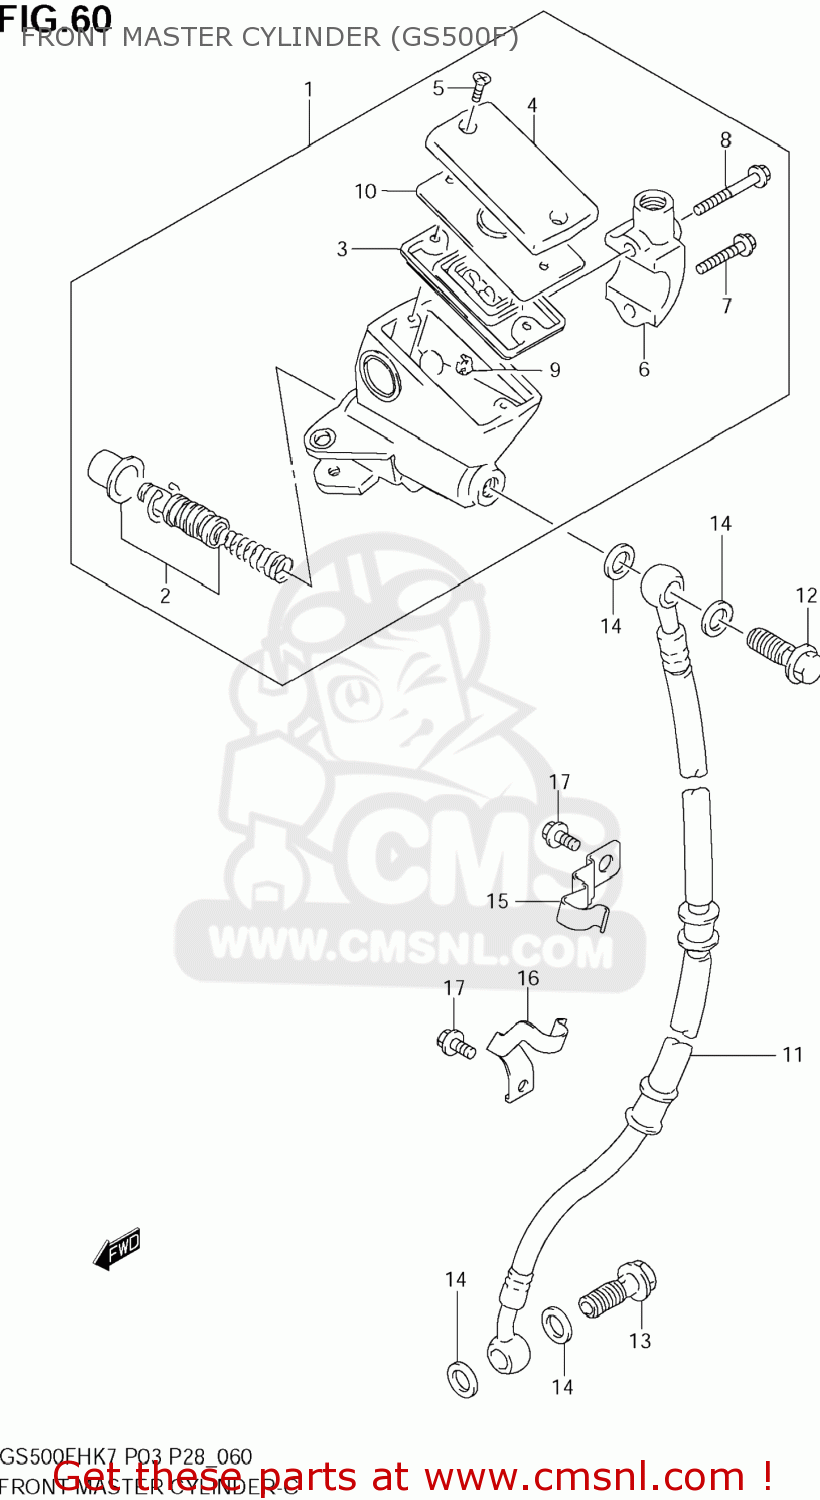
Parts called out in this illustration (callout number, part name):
1	CYLINDER ASSY
2	PISTON/CUP SET
3	DIAPHRAGM
4	CAP
5	SCREW
6	HOLDER
7	BOLT
8	BOLT UPPER
9	PROTECTOR
10	PLATE
11	HOSE, FR BRAKE
12	BOLT UNION
13	BOLT UNION
14	WASHER(10X15X1.5)
15	CLAMP, HOSE
16	CLAMP, HOSE
17	BOLT
